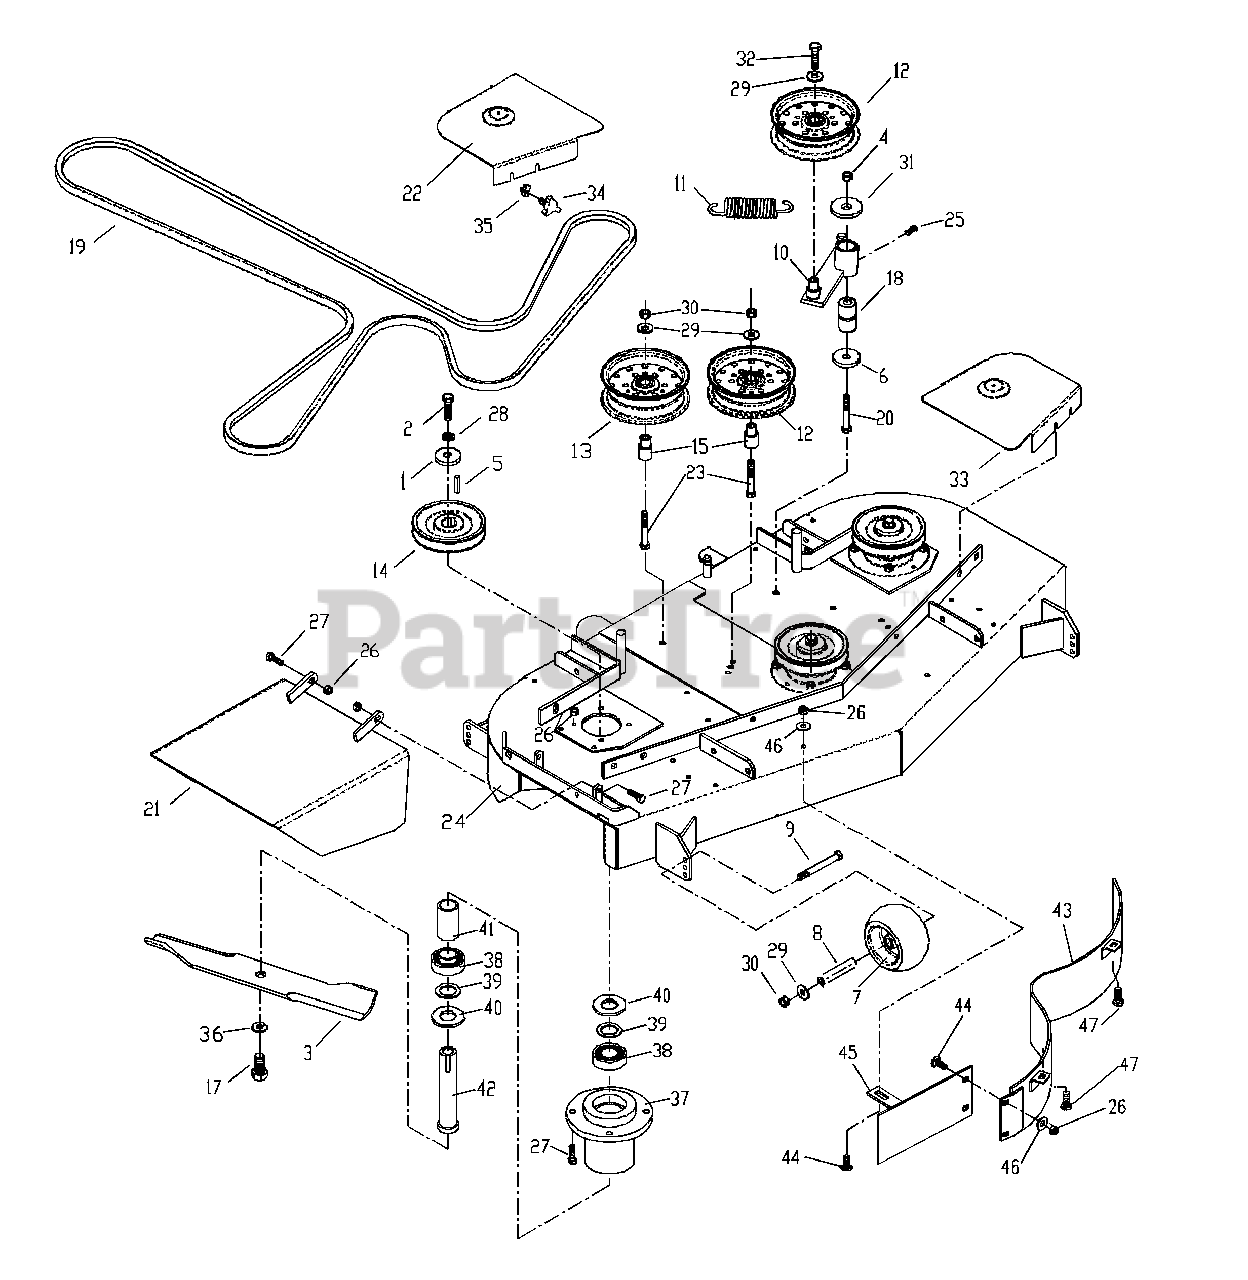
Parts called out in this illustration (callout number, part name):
1	HEAVY WASHER
2	HCS 7/16 X 1.500
3	BLADE 18.00
4	NUT 1/2 NYLOC
5	KEY 1/4 X 1.125
6	SUPPORT WASHER
7	ANTI-SCALP ROLLER
9	HCS 3/8 X 3.500
12	IDLER PULLEY
13	IDLER PULLEY
15	IDLER BUSHING
16	COMPLETE HOUSING
17	HCS 5/16 X 1.250
18	PIVOT BUSHING
19	BELT
20	HCS 1/2 X 3.250
21	DEFLECTOR CHUTE
22	BELT SHIELD
23	HCS 3/8 X 2.500
24	DECK W/DECALS
25	ZERK
26	NUT 5/16 CTR. LOCK
27	HCS 5/16 X 1.000
28	WASHER 7/16 LOCK
29	WASHER 3/8 FLAT
30	NUT 3/8 CTR. LOCK
31	WASHER 1/2 FLAT
32	HCS 3/8 X 1.00 SERR. HD.
33	BELT SHIELD
34	KNOB
36	WASHER 5/8 LOCK
38	BEARING
39	MACH. BUSHING
40	MACH. BUSHING
43	MAIN BAFFLE
44	RHSNB 5/16 X .625
45	CENTER BAFFLE
46	WASHER 5/16 FLAT
47	HCS 5/16 X .750
